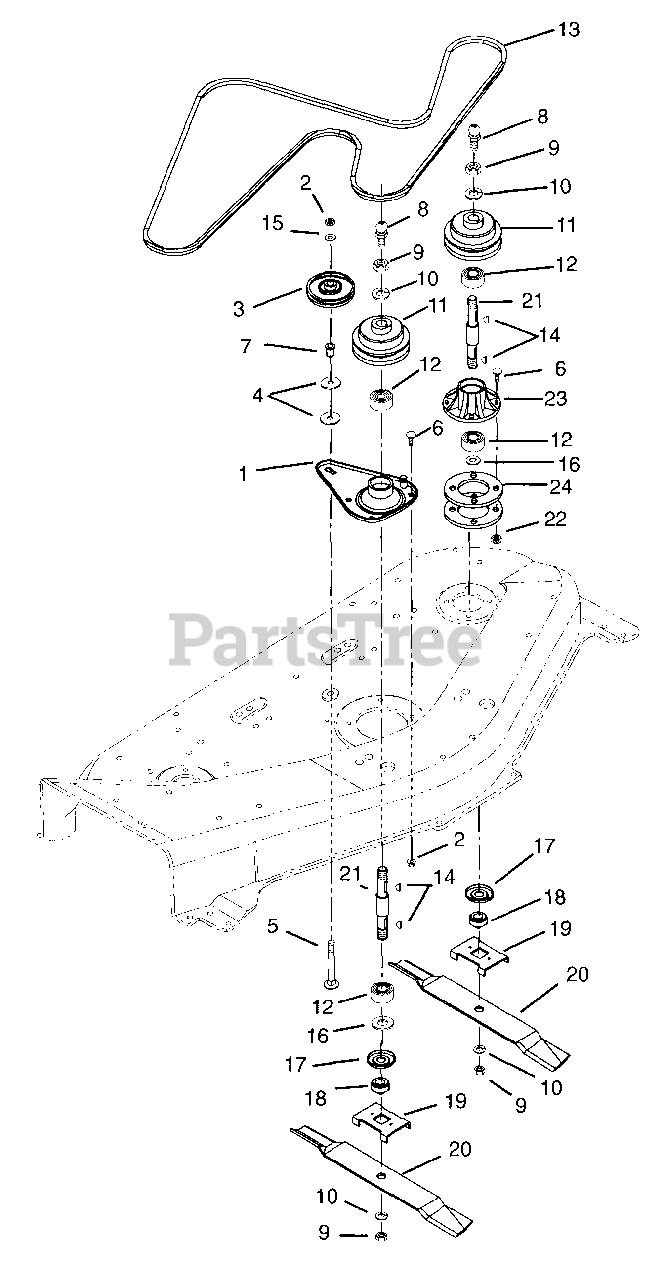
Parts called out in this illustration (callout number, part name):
1	HOUSING, SPINDLE
2	@NUT-LK-CTR .38-16 YWZC
3	IDLER, PLASTIC, 4.00 X .50 ID
4	WSHR-FL-STL .390X1.5X.125 YWZC
5	@BLT-RDHDSQNK .38-16X2.00 G2YZ
6	@BLT-RDHDSQNK .38-16X.75 G2YWZ
7	SPACER -FLANGED .390X.500X.781
8	FTG-LUBE .25-28X.256 YWZC
9	NUT-JAM .75-10 YWZC
10	@WSHR-LK .75X.188 REG YWZC
12	BRG-BALL .750X1.781X.61
13	V-BELT, HA-RAW EDGE
14	KEY-WDRF .188X.625X.25 SAE 61
15	@WSHR-FL-STL.38X.875X.083 YWZC
16	WSHR-FL-STL .754X1.000X.032 YZ
17	BEARING SLINGER
18	RETAINER HUB
19	BLADE TRAY 48
21	SPINDLE SHAFT W/ZERK
22	@NUT-LK-CTR-JAM .375-16 YWZC
23	SPINDLE HOUSING
24	SPACER, SPINDLE
